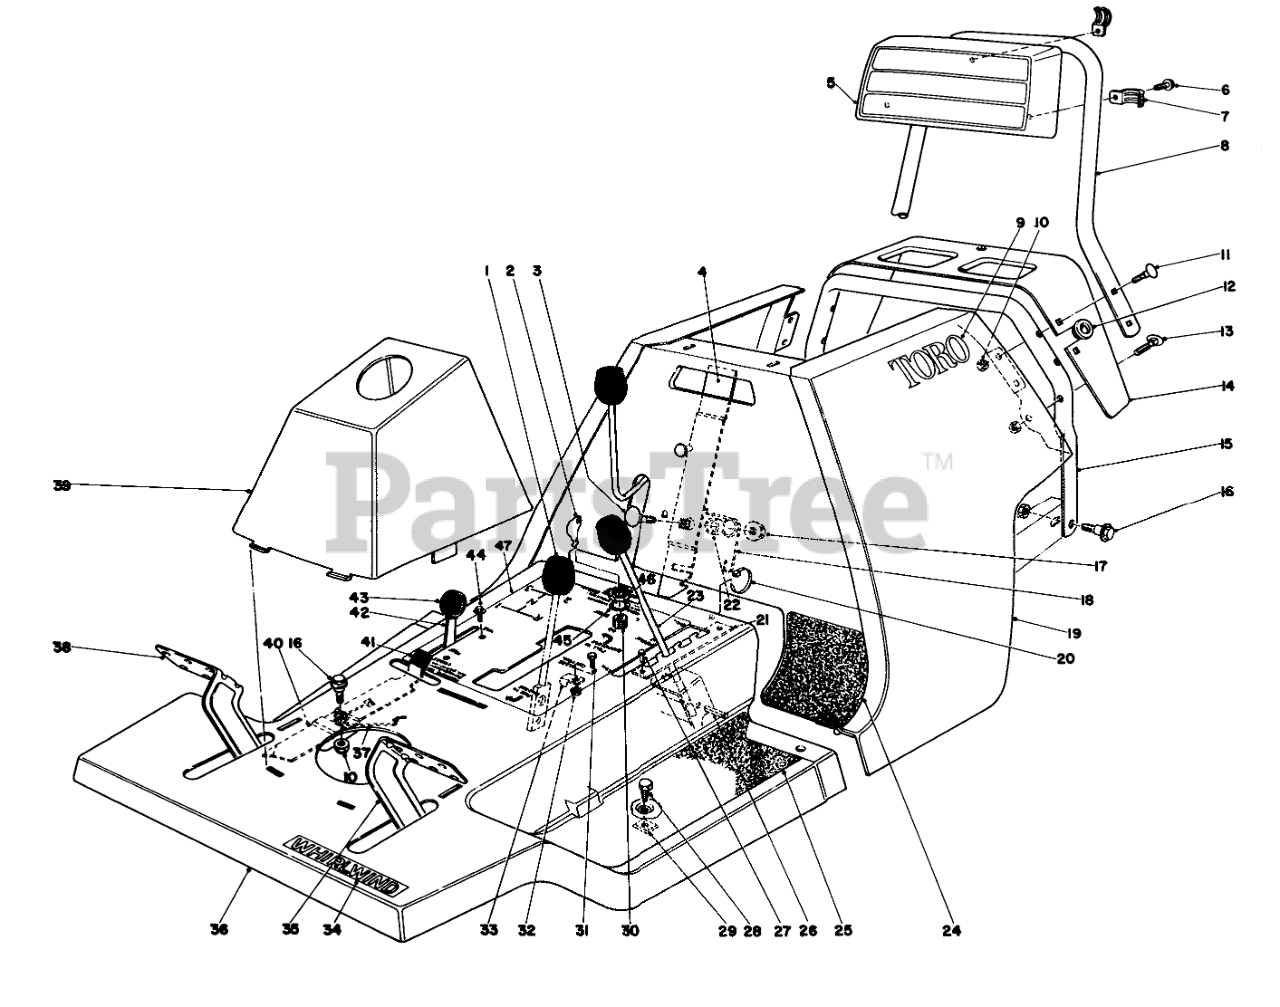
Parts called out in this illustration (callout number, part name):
2	Key
3	BOLT-CARR
4	Handle Latch
5	Backrest
6	SCREW-HHF
7	CLAMP-CONDUIT
8	Handle Upper
9	TORO LOGO DECAL
10	NUT-LOCK, CONE
11	SCREW-CARR
12	Starting Ferrel
13	HANDLE SCREW
14	Extension Rear Body
15	Handle Lower
16	SCREW-SHOULDER
17	NUT-HF
18	Latch Return Spring
19	Rear Body
20	TIE-CABLE
21	Height Adjustment Plate
22	Spacer
23	Height of Cut Lever
24	Heel Pad-LH.
25	Foot Tread LH.
26	PIN-SPECIAL
28	SCREW-HH
29	NUT-TINNERMAN
30	Starter Switch (Incl. Ref. #2, 45 & 46)
32	NUT-KEPS
33	CABLE CLAMP
34	WW DECAL
35	Clutch Pedal
36	Body Front (Incl. Ref. #21, 27 & 47)
37	SPRING-PARKING BRAKE
38	Brake Pedal
39	Tower
40	Parking Brake
41	TIP-PARKING BRAKE
42	Throttle Control (Incl. Ref. #43)
44	8X1/2 SELF TAP SCREW
45	WASHER-TOOTH, INTERNAL
46	NUT-HH
47	Decal-Front Body
